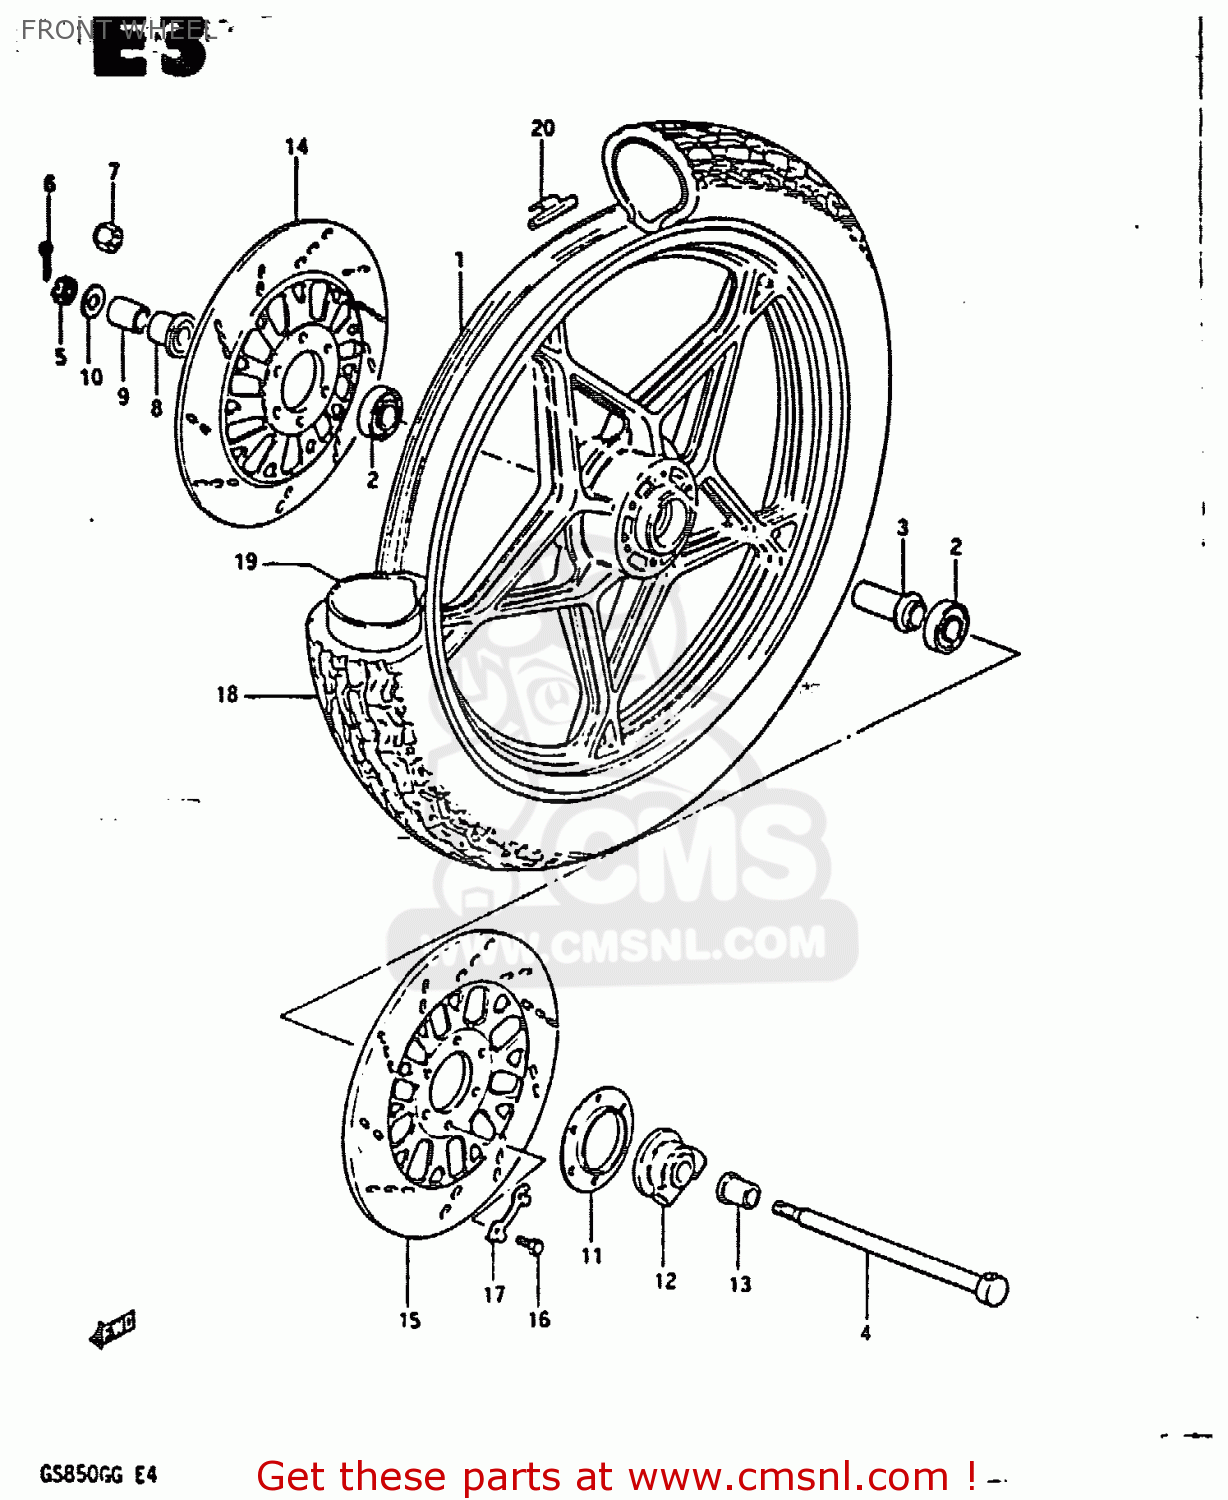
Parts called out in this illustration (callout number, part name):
1	CASTING WHEEL,FRONT 2.15
2	BEARING
3	SPACER,FR HUB BEARING
4	AXLE,FR
5	NUT 12MM
6	COTTER PIN
7	NUT
8	SPACER,FR AXLE,R
9	SPACER,FR AXLE,R
10	WASHER
11	DUST SEAL,SPEEDOMETER GEAR BOX
12	BOX ASSEMBLY,SPEEDOMETER GEAR
13	SPACER,FR AXLE,L
14	DISC,FR BRAKE,R
15	DISC,FR BRAKE,L
16	BOLT(8X25)
17	WASHER
18	TIRE (3.50H19)
19	TUBE,INNER
20	BALANCER,WHEEL
